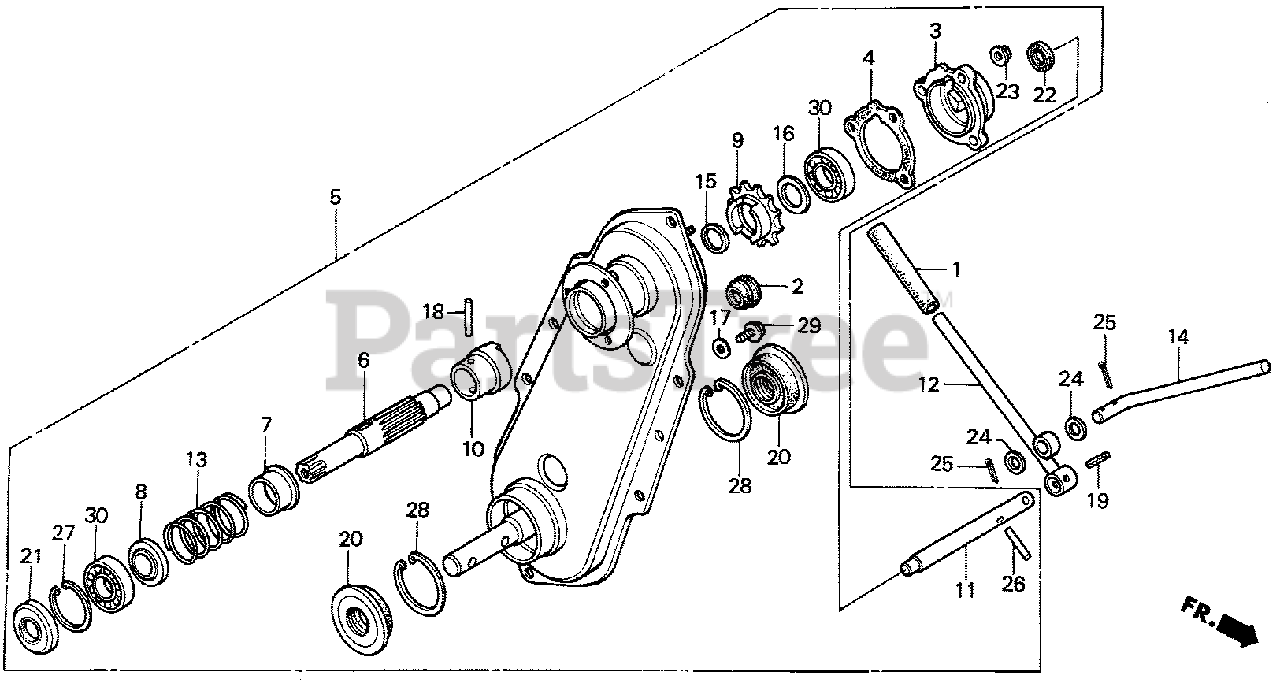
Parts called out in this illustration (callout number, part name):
1	GRIP, LEVER
2	GROMMET, ROTARY
3	METAL, CLUTCH (NOT AVAILABLE)
4	GASKET, CLUTCH METAL
5	TRANSMISSION ASSY., SECONDARY
5	TRANSMISSION ASSY., SECONDARY (NOT AVAILABLE)
6	SHAFT, CLUTCH
7	RETAINER A, CLUTCH SPRING
8	RETAINER B, CLUTCH SPRING
9	SPROCKET, SECONDARY DRIVE (11T)
10	SHIFTER, CLUTCH
11	SHAFT, CLUTCH RELEASE
12	LEVER, CLUTCH
13	SPRING, CLUTCH
14	BAR, REVERSE STOP
15	WASHER, THRUST (22MM)
16	WASHER, THRUST (20X1.00)
17	WASHER, SEALING (6.5X12)
18	PIN, ROTARY CLUTCH (5X33.5)
19	PIN, ROLLER (6X36)
20	SEAL, WATER (30X62X14)
21	OIL SEAL (20X52X6)
22	OIL SEAL (12X21X5)
23	NUT, FLANGE (8MM)
24	WASHER, PLAIN (8MM)
25	PIN, COTTER (2.0X15)
26	PIN, SPRING (6X18) (NOT AVAILABLE)
27	CIRCLIP (INNER) (52MM)
27	CIRCLIP (INNER) (50MM)
28	CIRCLIP (INNER) (62MM)
29	BOLT, FLANGE (6X10)
30	BEARING, RADIAL BALL (6304)
